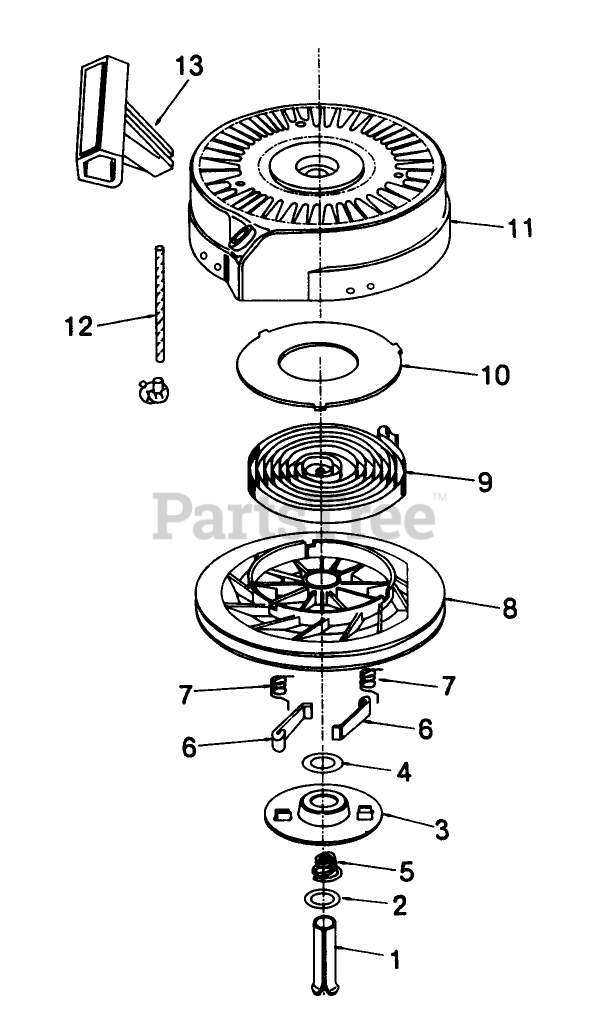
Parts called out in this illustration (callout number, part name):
1	Pin Spring
2	Washer
3	Retainer
4	Washer
5	Brake Spring
6	Dog-Starter
7	Spring-Dog
8	Pulley
9	Rewind Spring
10	Cover-Spring
11	Housing-Starter
12	Rope-Starter (98 cut to length)
13	Handle-Starter
